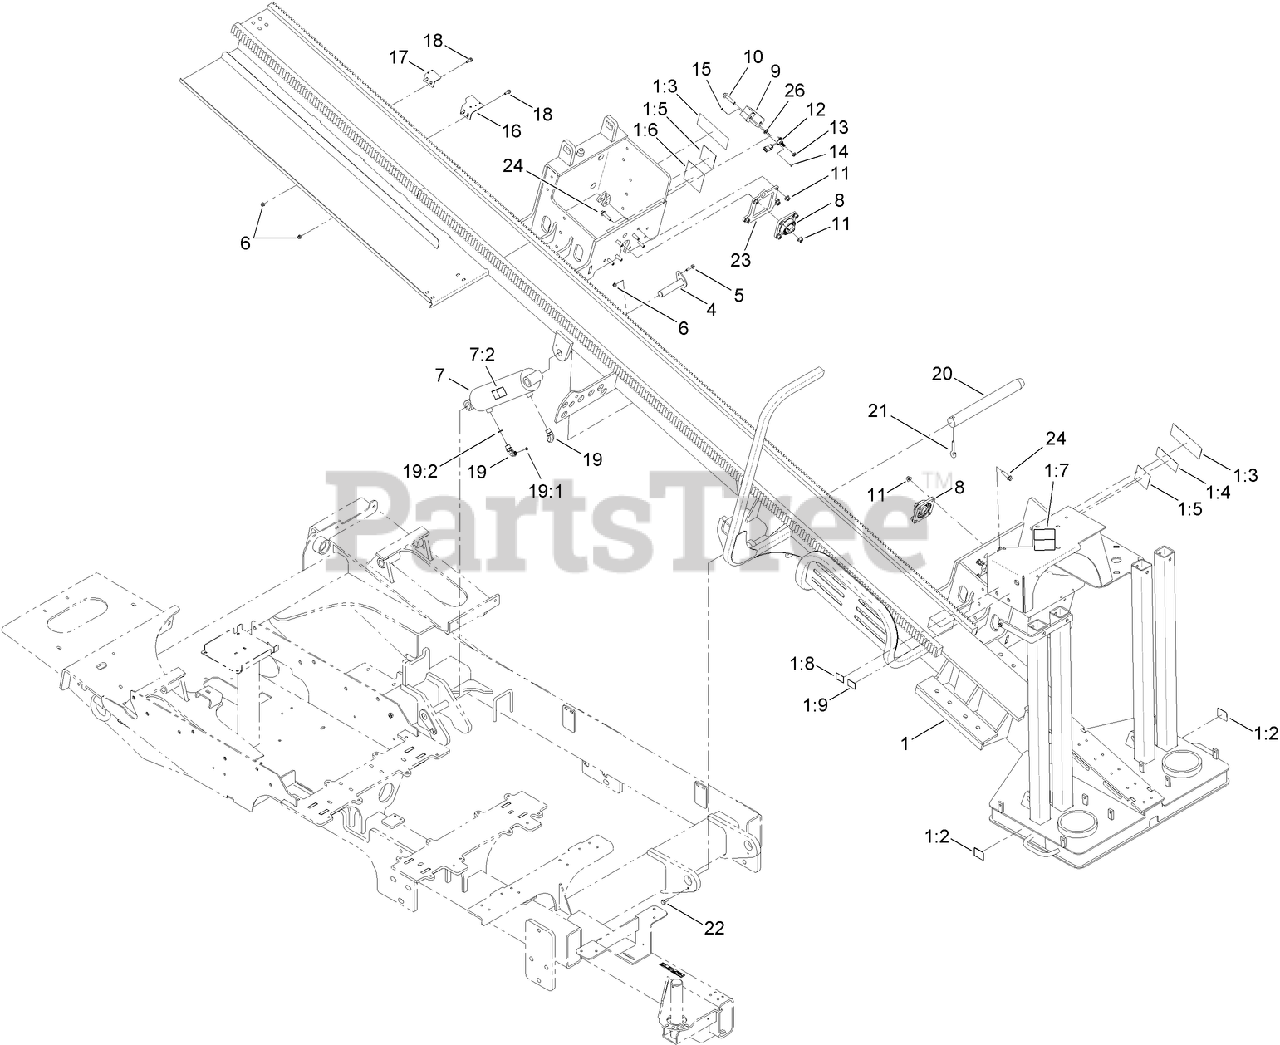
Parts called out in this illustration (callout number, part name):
1	THRUST FRAME ASM
1:2	DECAL-TIE DOWN
1:3	DECAL-DANGER, HAZARDOUS AREA
1:4	DECAL-WARNING, HYDRAULIC PRESSURE
1:5	DECAL-WARNING, CRUSHING
1:6	DECAL-SHOCK DANGER
1:7	DECAL-STAKEDOWN SET UP
1:8	DECAL-PIPE RETURN, CLEAR
1:9	DECAL-PIPE BREAKOUT, CLEAR
4	PIN-PIVOT
5	SCREW-HHF
6	NUT-LOCK, HHF
7	LIFT CYLINDER ASM
7:2	DECAL-CAUTION, CYLINDER LOCK
8	BEARING-FLANGED Y, SQUARE
9	PLATE-MOUNTING
10	SCREW-HHF
11	NUT-LOCK, HHF
12	SENSOR-ROTARY
13	NUT-HEX
15	NUT-HEX, KEPS
16	PLATE-MOUNT, PROXIMITY SWITCH
17	PLATE-MOUNT, SWITCH
18	SCREW-HHF
19	FITTING-ELBOW 90
19:1	O-RING
19:2	O-RING
20	PIN-PIVOT, MAIN
21	PIN-RETAINER
22	SCREW-HHF
23	PLATE-SUPPORT, BEARING
24	SCREW-HHF
26	WASHER-FLAT
